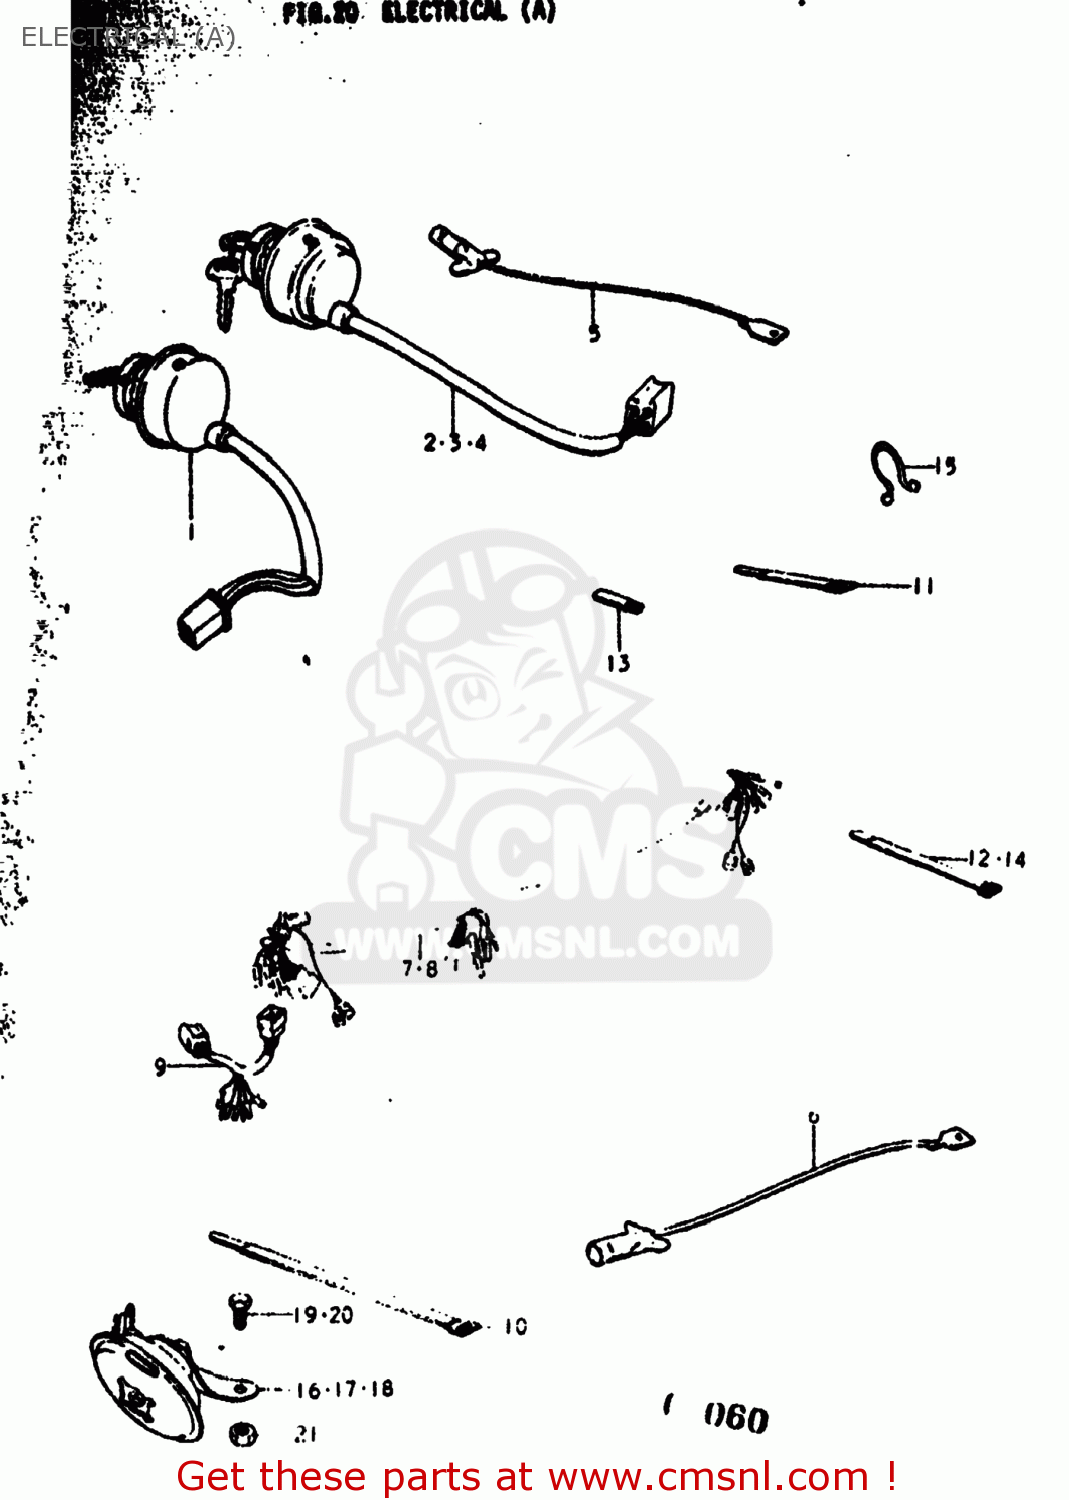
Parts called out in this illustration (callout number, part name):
1	SWITCH ASSEMBLY,IGNITION
2	SWITCH ASSEMBLY,IGNITION
3	SWITCH ASSEMBLY,IGNITION
4	SWITCH ASSEMBLY,IGNITION
6	WIRE,WIRING HARNESS LEAD
7	HARNESS,WIRING
8	HARNESS,WIRING
9	WIRE,TURN SIGNAL LEAD
10	CLAMP(L:250)
11	CLAMP
12	CLAMP
13	CLAMP
14	CLAMP(L:120)
15	CLAMP
16	HORN K,L
17	HORN ASSEMBLY
18	HORN ASSEMBLY
19	BOLT(6X8)
20	BOLT(6X6)
21	NUT K,L
